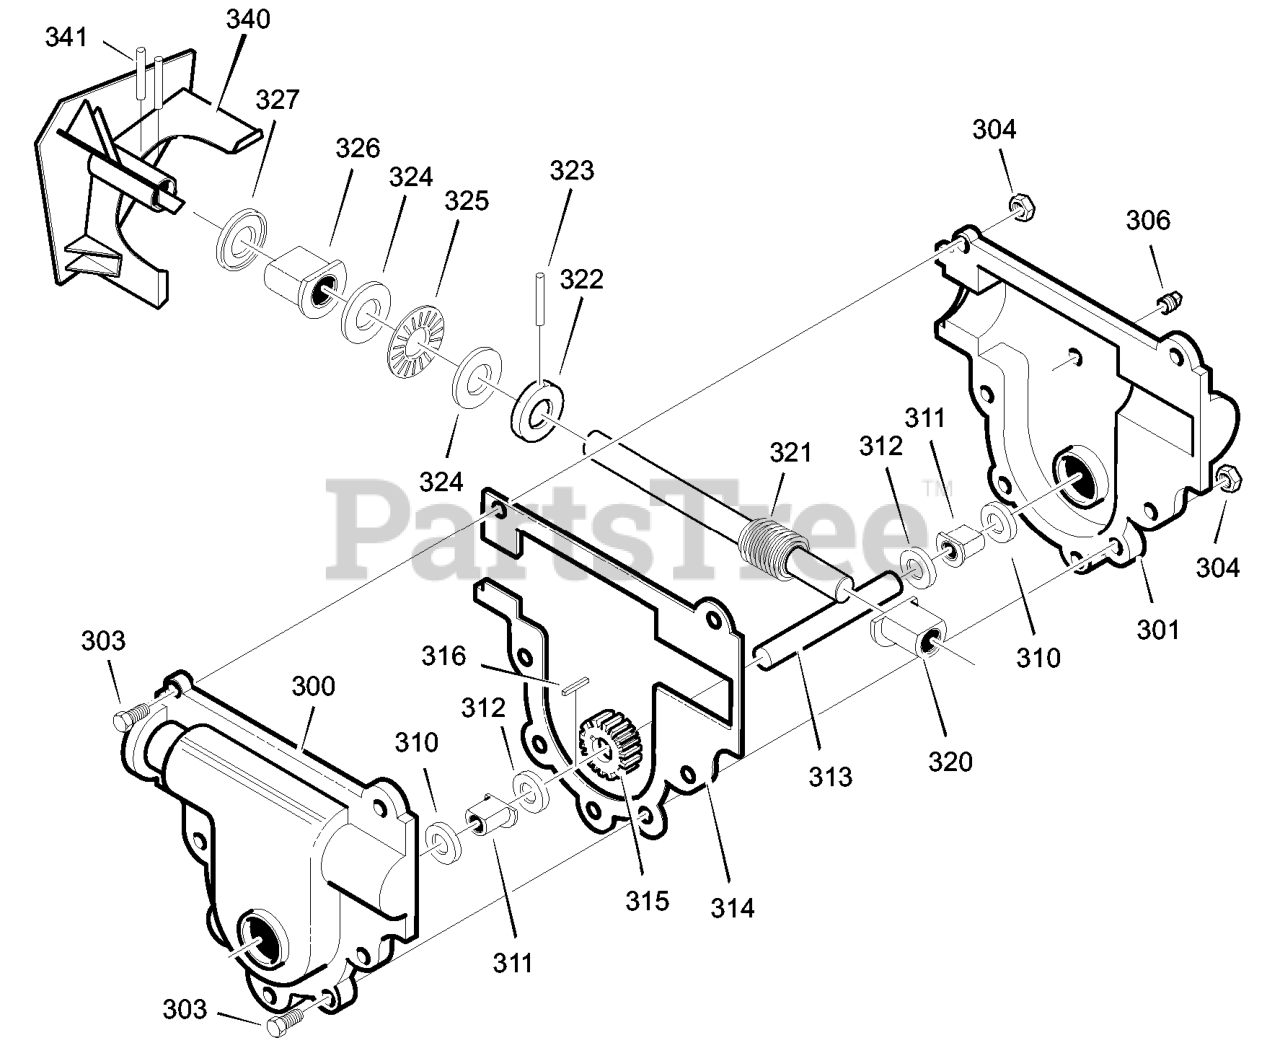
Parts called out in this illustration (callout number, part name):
300	CASE, GEAR, RH
301	CASE, GEAR, LH
306	SCREW
310	SEAL, OIL
311	BEARING, FL
312	WASHER, FLAT
313	SHAFT, OUTPUT
315	GEAR, WORM
316	KEY, WOODRUFF
320	BRNG, FL
321	SHAFT, INPUT
322	COLLAR, THRUST
323	PIN, SPRING
324	WASHER, FLAT
325	BRNG, ROLL
326	BRNG, FL
327	SEAL, OIL
340	IMPELLER ASSEMBLY
341	PIN, SPRING
